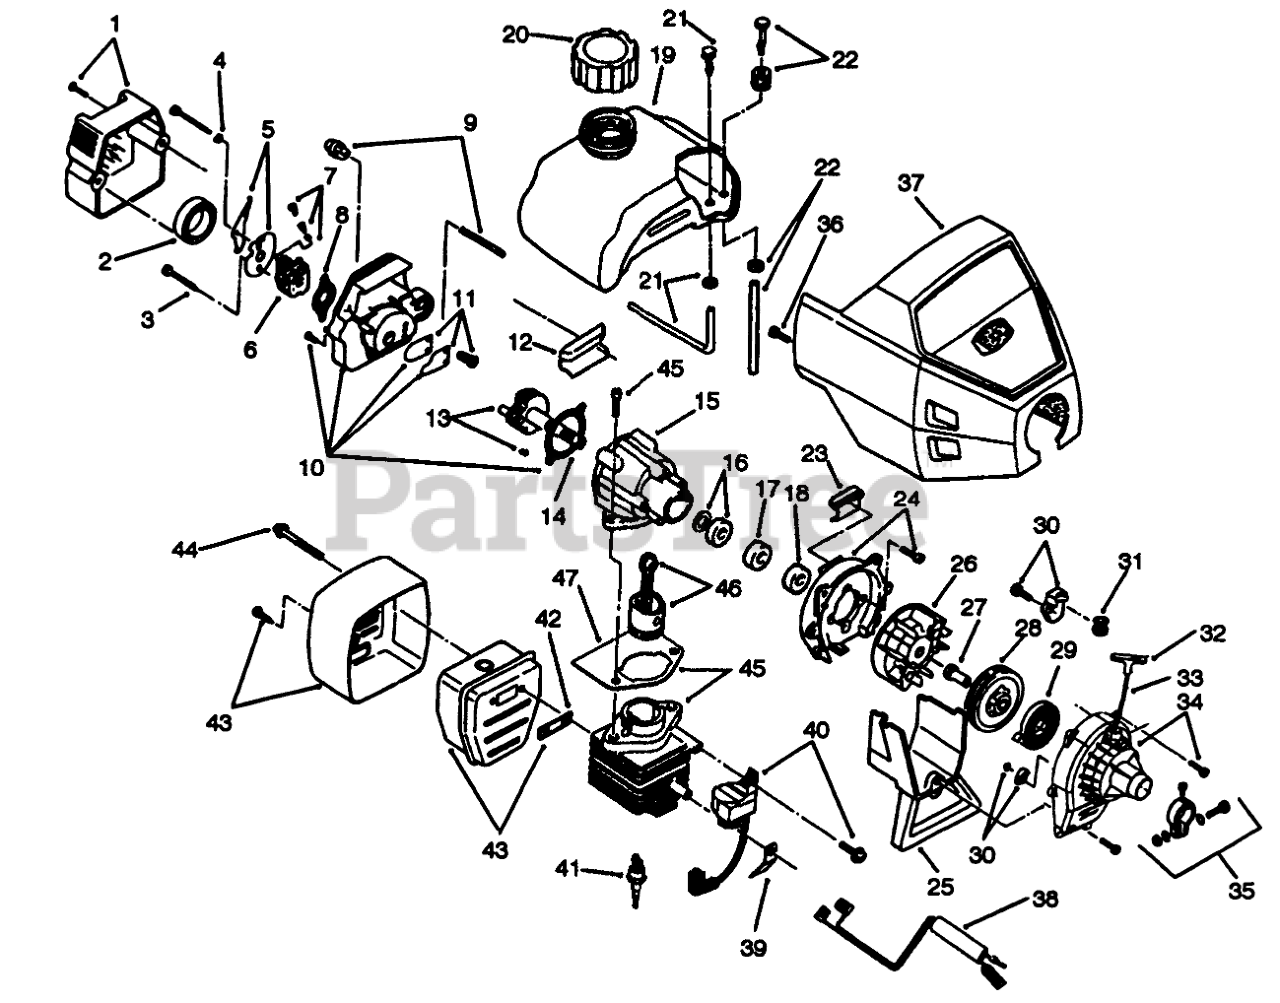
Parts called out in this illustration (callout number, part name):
1	Assy.-Carburetor/Air Clean. (Inc. Ref. No.2)
2	AIR CLEANER FILTER
3	CARB MTG SCREW ASM
4	WAVEY WASHER
5	CHOKE LEVER & PLATE
6	Carburetor
7	THROTTLE ADJ ASM
8	CARBURETOR GASKET(10 PER PACK)
9	PRIMER & HOSE ASM
10	Assembly-Carb. Mount (Incl. Ref. 11 & 12)
11	REED ASM
12	REAR MOUNTING PAD
13	POWER SHAFT ASM
14	CARB MT GASKET (10-PK)
15	Assy.-Crankcase (Incl. Ref. No.14-18)
16	INNER BEARING ASM
18	OUTER BEARING
19	Assemby-Fuel Tank (Incl Ref. No.20-22)
20	FUEL CAP ASM
21	FUEL RETURN LINE ASM
22	FUEL LINE ASM
23	FRONT MOUNTING PAD
24	SHROUD ASM
25	Shroud Extension & Stand
26	Assembly-Flvwheel
27	SQUARE DRIVE NUT
28	RECOIL PULLEY ASM
29	RECOIL SPRING
30	Pulley Retainer Asm.
31	ROPE GUIDE
32	Handle-Pull
34	STARTER HSG ASM
35	CLAMP ASM - UPPER
36	ENGINE COVER SCREWS
37	ENGINE COVER ASM
38	LEAD WIRE ASM
39	GROUND TAB
40	Module Asm.
41	SPARK PLUG
42	Exhaust Gasket
43	MUFFLER ASM
44	MUFFLER MTG BOLT ASM
45	Throttle Lever
46	PISTON & ROD ASM
47	CYLINDER GASKET
